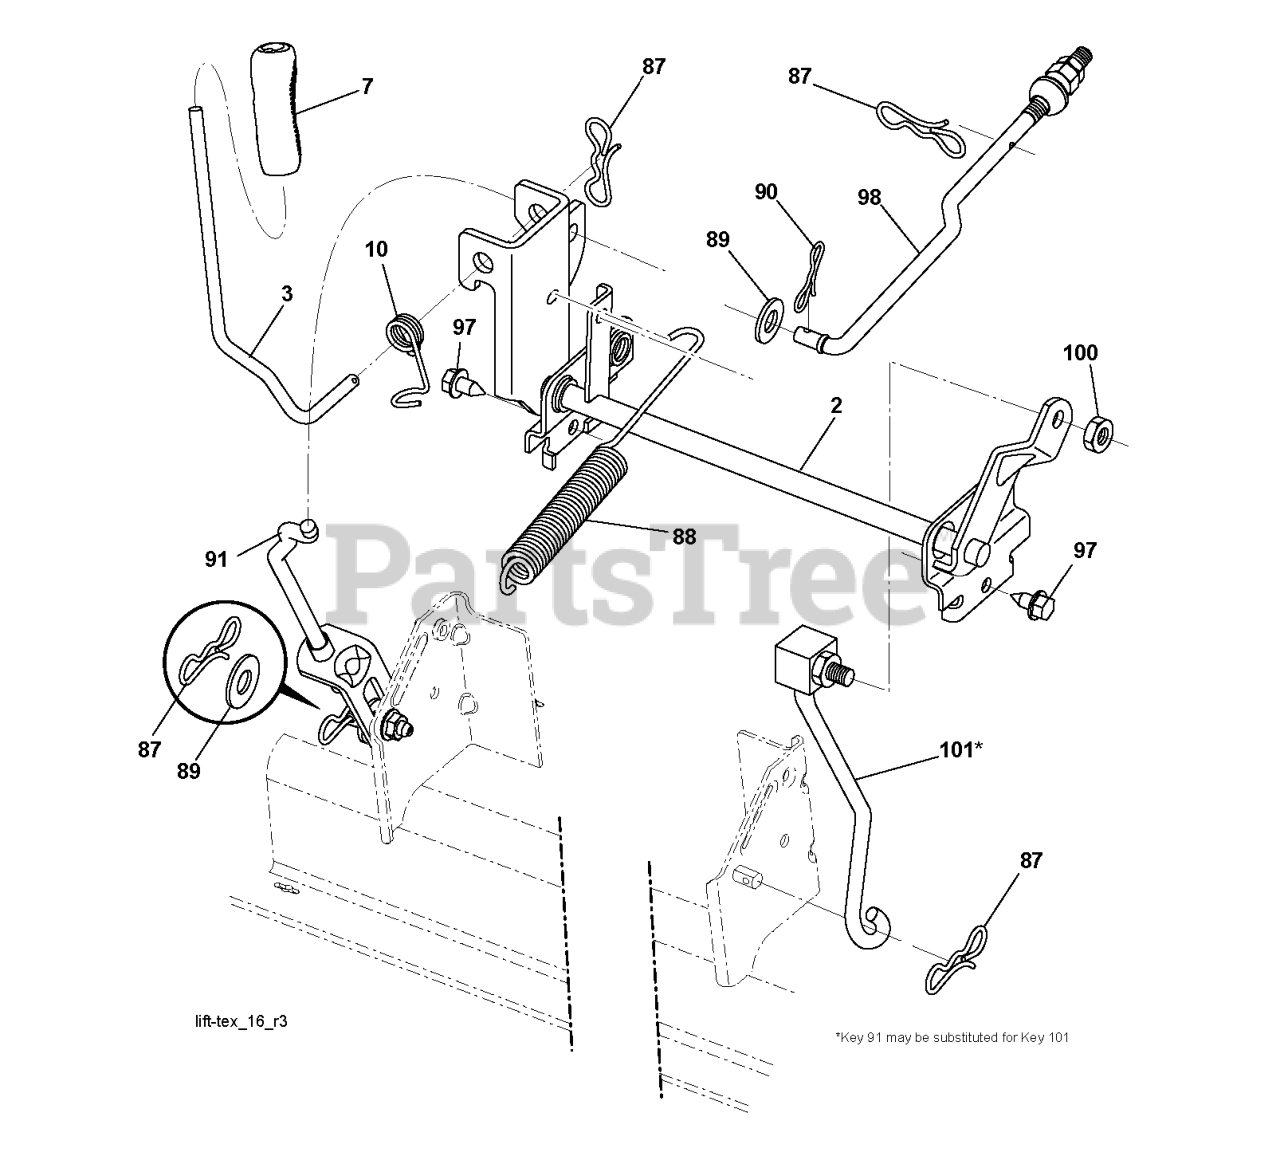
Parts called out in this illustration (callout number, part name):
2	SHAFT.ASM.CROSS.LIFT
3	LEVER.LIFT.HANDLE.GT
7	GRIP.HANDLE.LIFT.PVC.BLACK
10	SPRING.TORSION.LIFT.HANDLE
87	PIN.COTTER.7/16.BOW TI.
88	SPRING.LIFT.ASSIST
89	WASHER.CLEAR.ZINC
90	PIN.COTTER.5/16.BOW TI
91	LINK.ASM.LIFT.REAR
97	SCREW, 3/8-16X3/4
98	LINK.ASM.SUSP.FRONT.MW
100	LOCKNUT
101	LINK.ASM.LIFT.FIXE.38/42/46"
